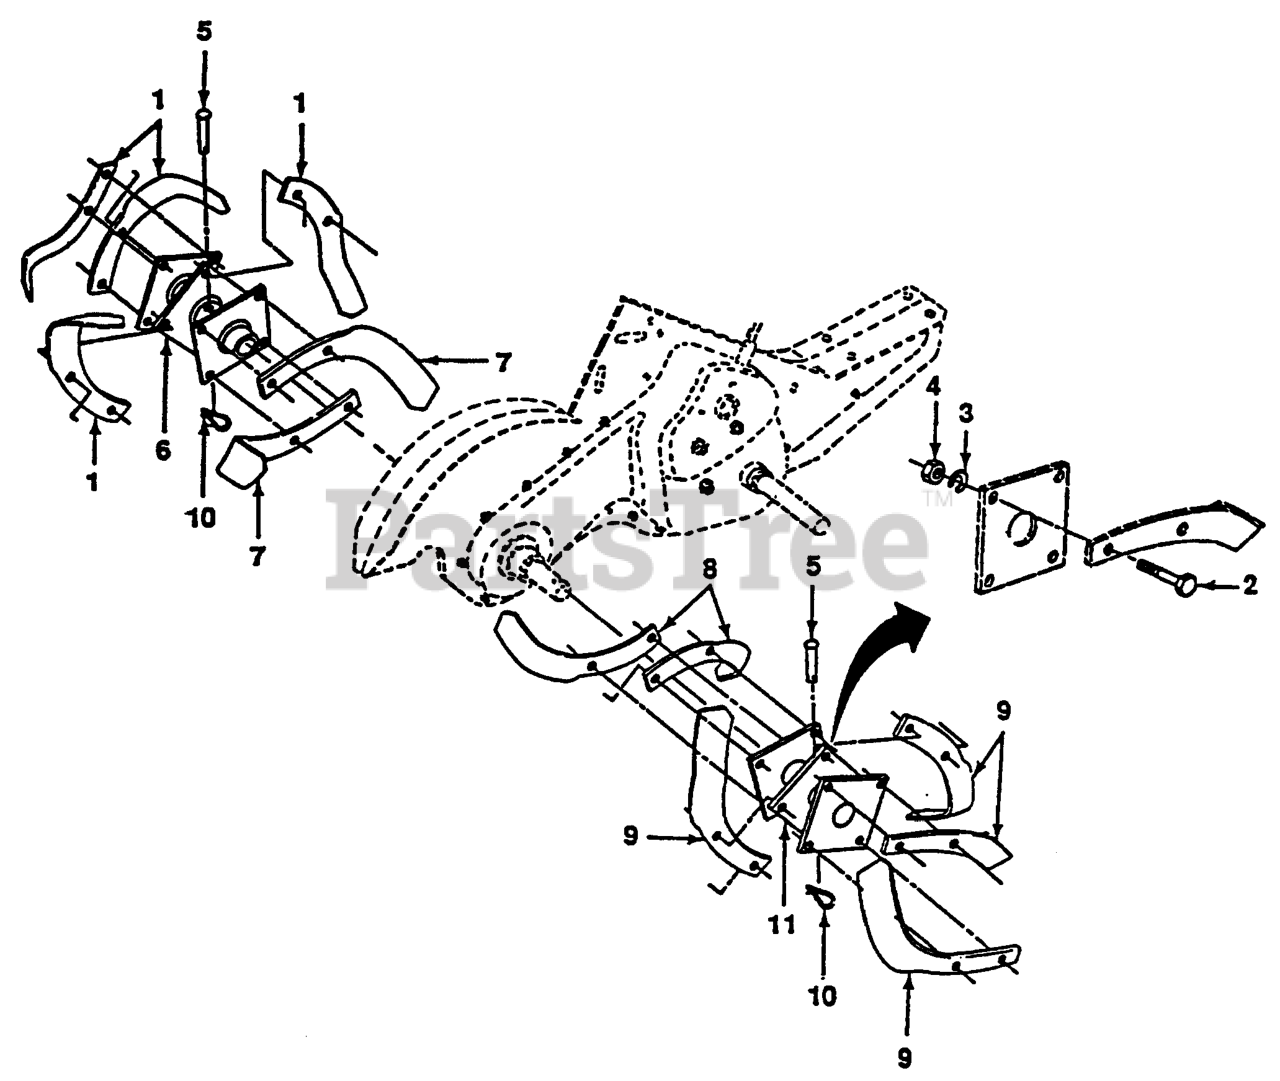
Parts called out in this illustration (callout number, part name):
1	TINE TI
2	BOLT.HEX.001X20.37-24X1.ZINC
3	WASHER, LOCK 3/8
4	NUT
6	TINE ASSY LH CRT NLA
7	TINE.LH.12"(72L)
8	TINE.RH.12"(72R)
9	TINE TI
10	SPRING RETAINER
11	TINE ASSY RH CRT
